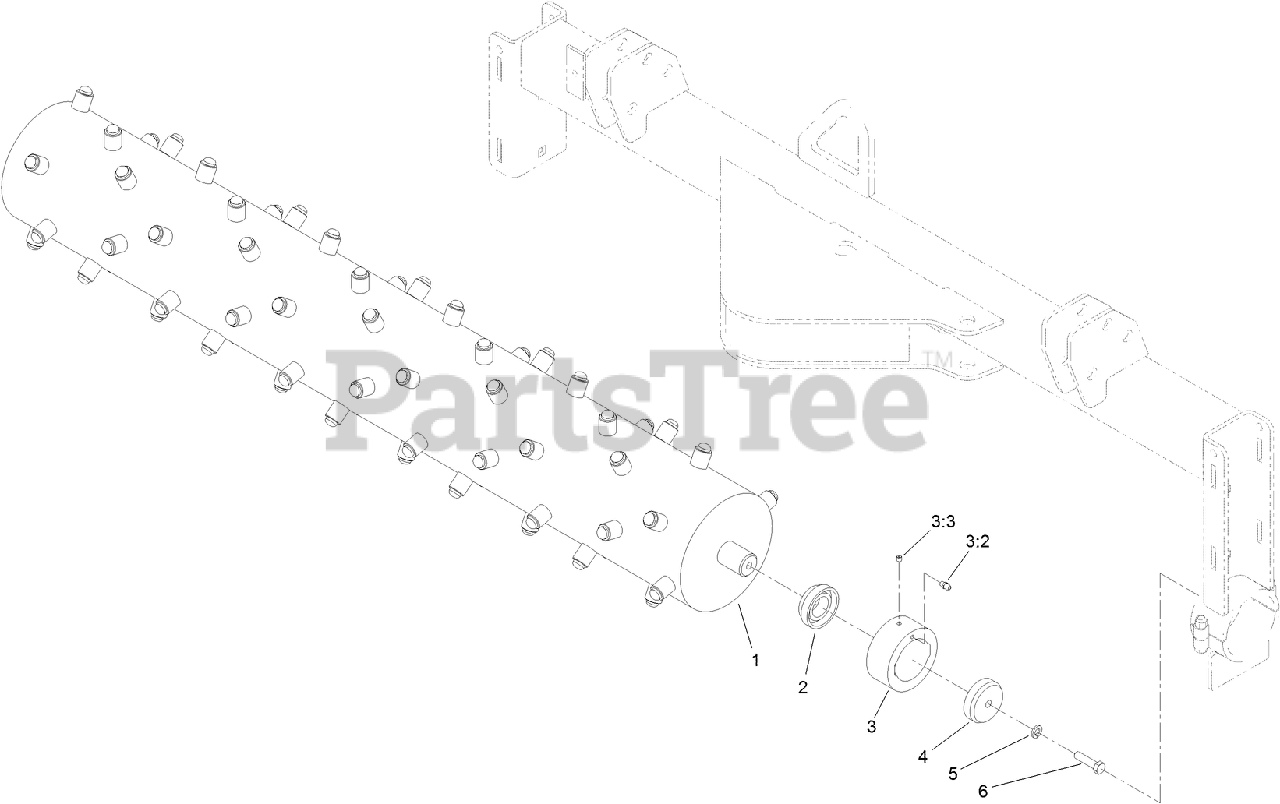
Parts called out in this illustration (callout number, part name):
1	ROLLER-TOOTH
2	BEARING-COLLAR
3	DRIVE BEARING ASM
3:2	SCREW-SET, HSH
3:3	FITTING-GREASE
4	BEARING-CAP
5	WASHER-LOCK
6	SCREW-HH
